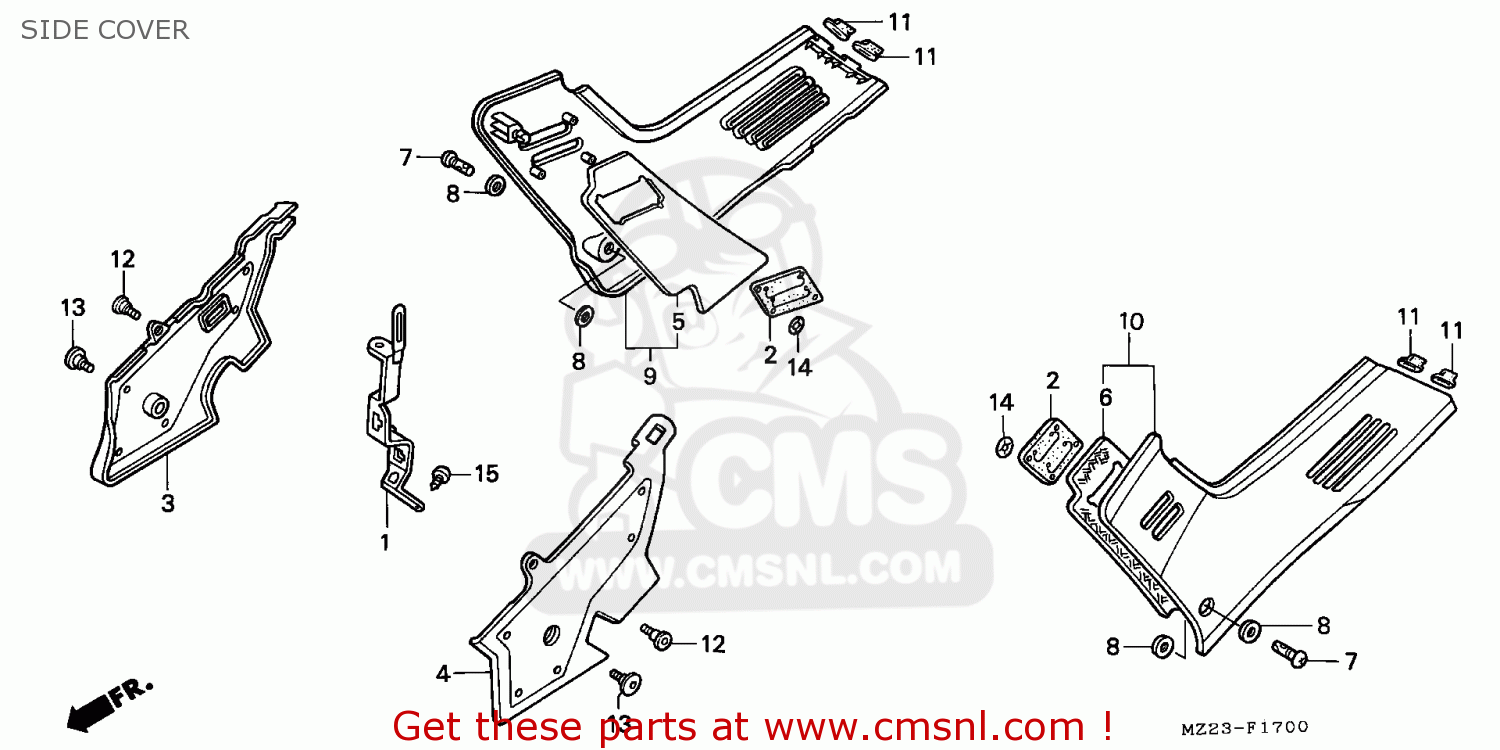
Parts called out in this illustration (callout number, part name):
1	HOLDER B,COUPLER
2	GUARD,SIDE COWL H
3	COVER COMP.,R PIV
4	COVER COMP.,L PIV
5	MAT,R.HEAT GUARD
6	MAT,L.HEAT GUARD
7	STUD,6X14
8	RETAINER,6MM
9	SET ILLUS*TYPE26*
10	SET ILLUS*TYPE26*
11	RUBBER,SIDE COWL
12	SCREW,PAN,6X11
13	SCREW,PAN.6X17
14	WASHER,SPECIAL,6M
15	SCREW,TAP. 5X8
